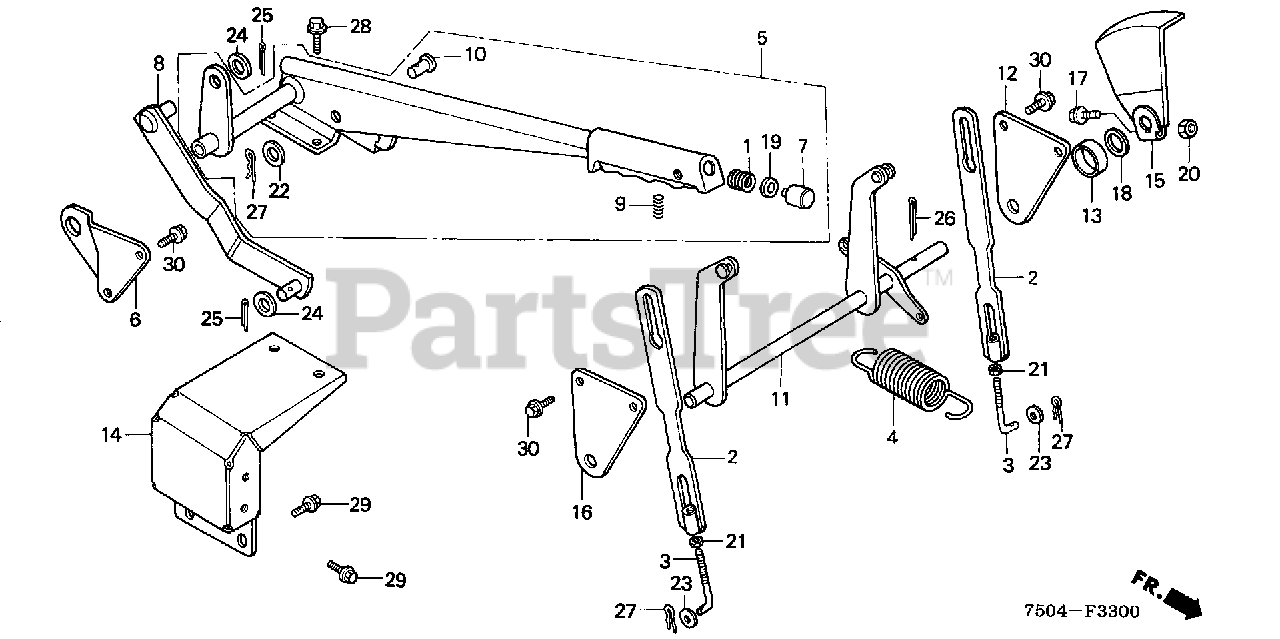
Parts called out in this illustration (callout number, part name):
1	SPRING, PUSH ROD
2	ROD, CUTTER DECK LIFT
3	BOLT, LIFT ROD ADJUSTING
4	SPRING, DECK LIFT (NOT AVAILABLE)
5	LEVER ASSY., HEIGHT ADJUSTING
5	LEVER ASSY., HEIGHT ADJUSTING (NOT AVAILABLE)
7	GRIP KIT, DECK ADJUST
7	KNOB, PUSH ROD
8	LINK, HEIGHT ADJUSTING ROD
9	SPRING, PUSH ROD
10	PIN, HEIGHT ADJUSTING LEVER STOPPER
11	SHAFT, LIFT
12	STAY, L. LIFT SHAFT
14	BRACKET, HEIGHT ADJUSTING LEVER
15	INDICATOR, HEIGHT ADJUSTING
16	STAY, R. LIFT SHAFT
17	BOLT, FLANGE (6X40)
18	WASHER, PLAIN (22MM)
19	WASHER (11MM)
20	NUT, HEX. (6MM)
21	NUT, HEX. (10MM)
22	WASHER, PLAIN (10MM)
23	WASHER, PLAIN (10MM)
24	WASHER, FLAT (12MM)
25	PIN, COTTER (3.0X45)
26	PIN, COTTER (4.0MM)
27	PIN, LOCK (10MM)
28	BOLT, FLANGE (8X14)
29	BOLT, FLANGE (8X16)
30	BOLT, FLANGE (8X16)
